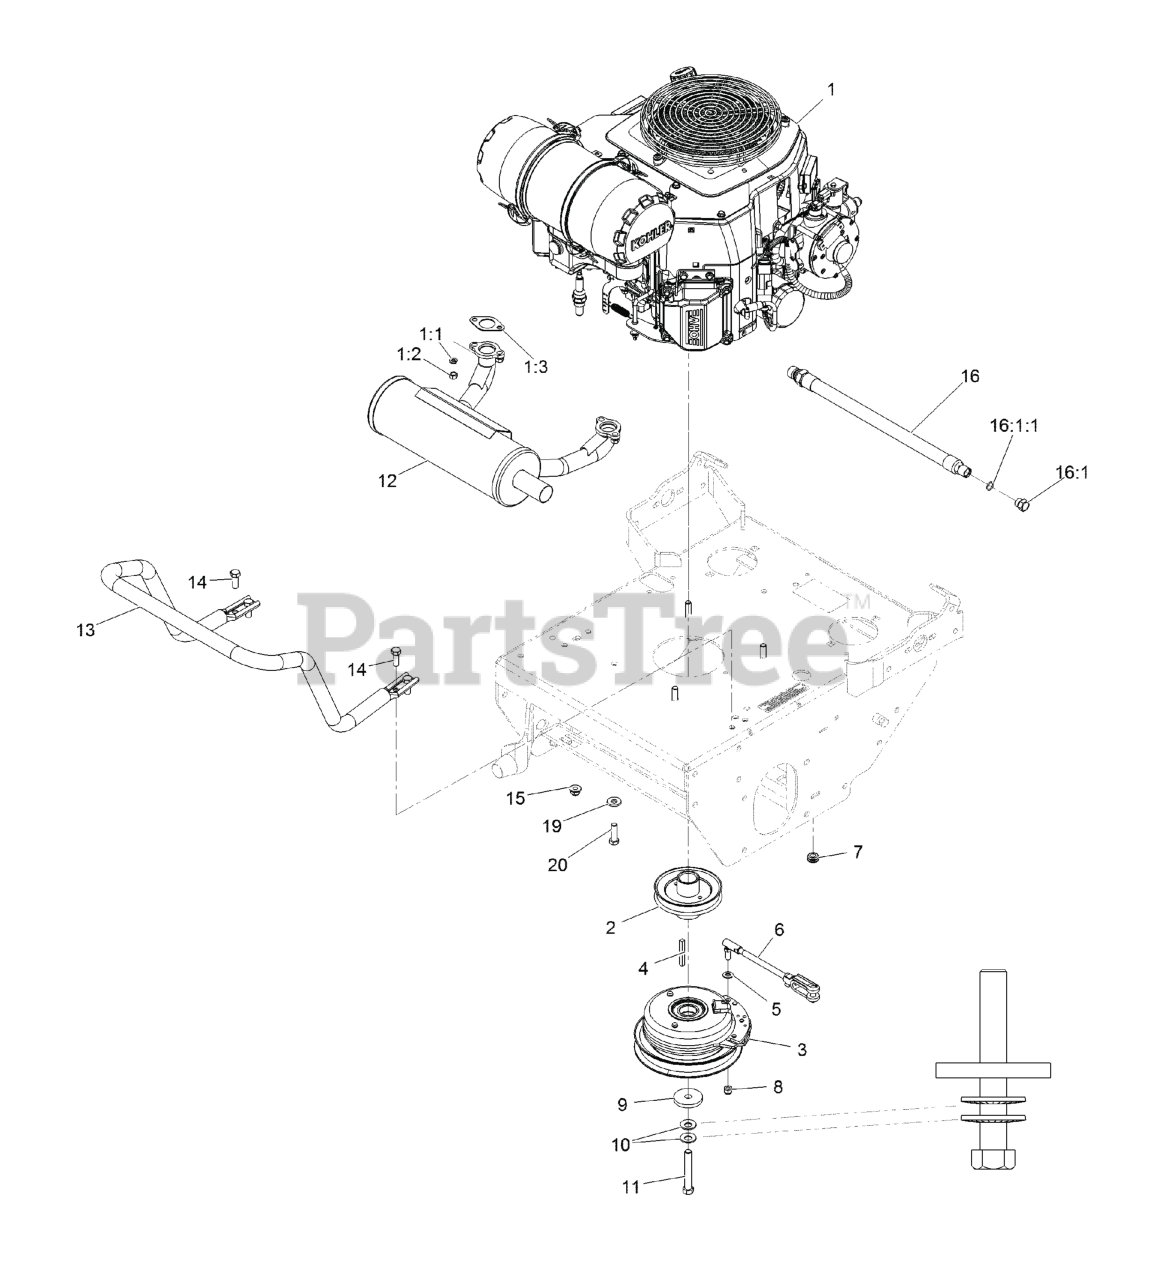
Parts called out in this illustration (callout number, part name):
1:1	WASHER-LOCK
1:3	GASKET-EXHAUST
2	SHEAVE, W/ HUB
3	CLUTCH, 105 FT/LBS, 1.13
4	KEY-SQUARE
5	WASHER-PLAIN
6	ASM, CLUTCH ANCHOR
7	GROMMET
8	NUT-LOCK
9	WASHER-CLUTCH
10	WASHER-SPRING
11	SCREW-HH
12	MUFFLER-HORIZONTAL
13	Guard-Muffler
14	SCREW-HH
15	NUT-HF, NI
16	ASM, ENGINE OIL DRAIN HOS
16:1	PLUG-HH
16:1:1	O-RING
19	WASHER-BELLEVILLE
20	SCREW-HH
